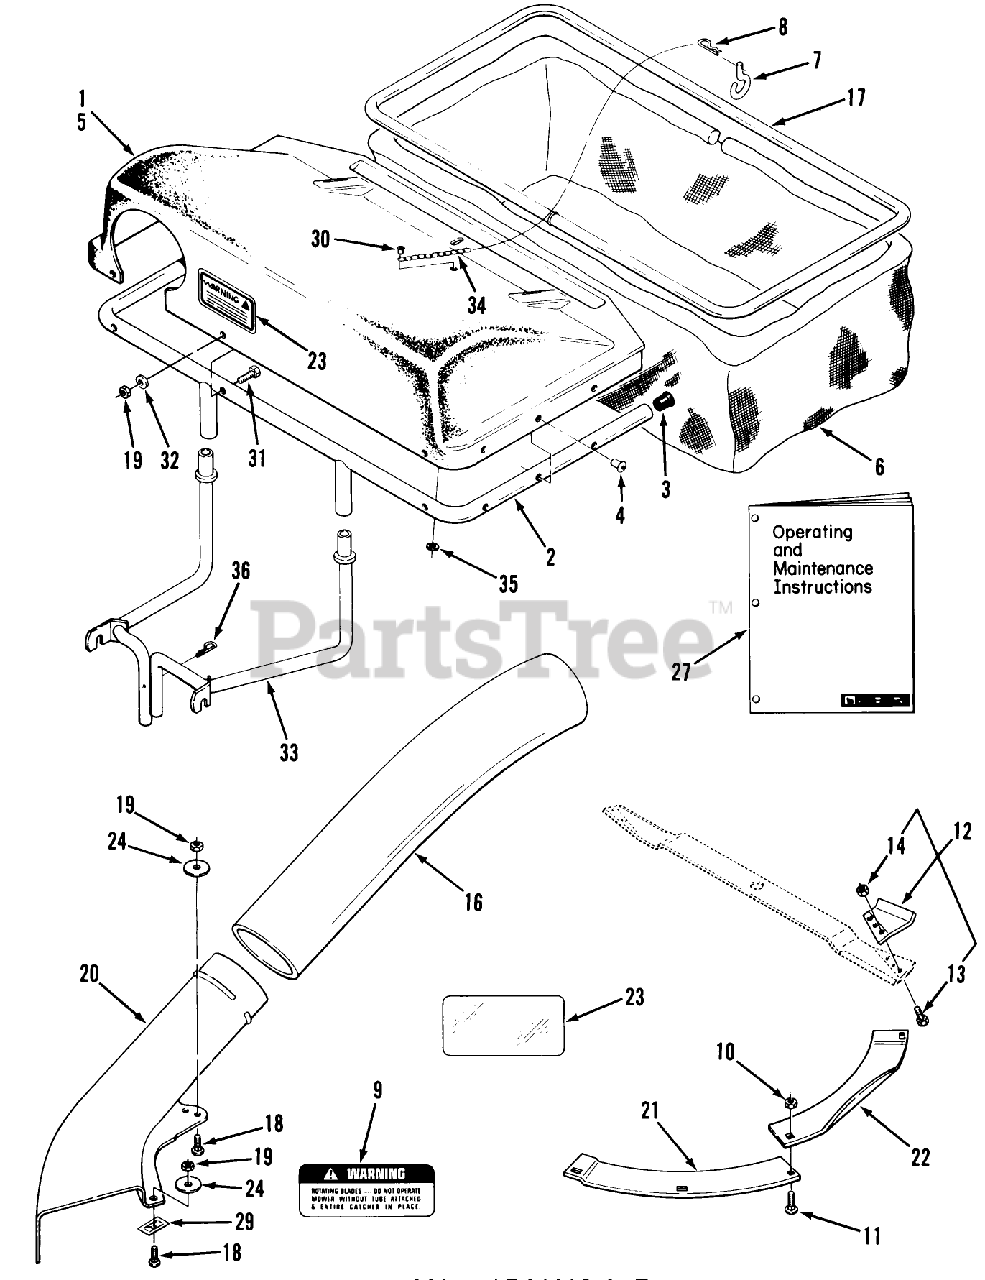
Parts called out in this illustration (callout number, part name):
8	Hairpin Cotter
12	S/A LIFT TAB KIT
13	BOLT 5/16-18X5/8
14	NUT-HEX
17	FRAME-BAG *B
22	PLATE MOWER *B
23	DECAL-OVERLAY
24	WASHER
27	Operating and Maintenance Instructions
29	SPEED NUT
30	RIVET
36	Hairpin
